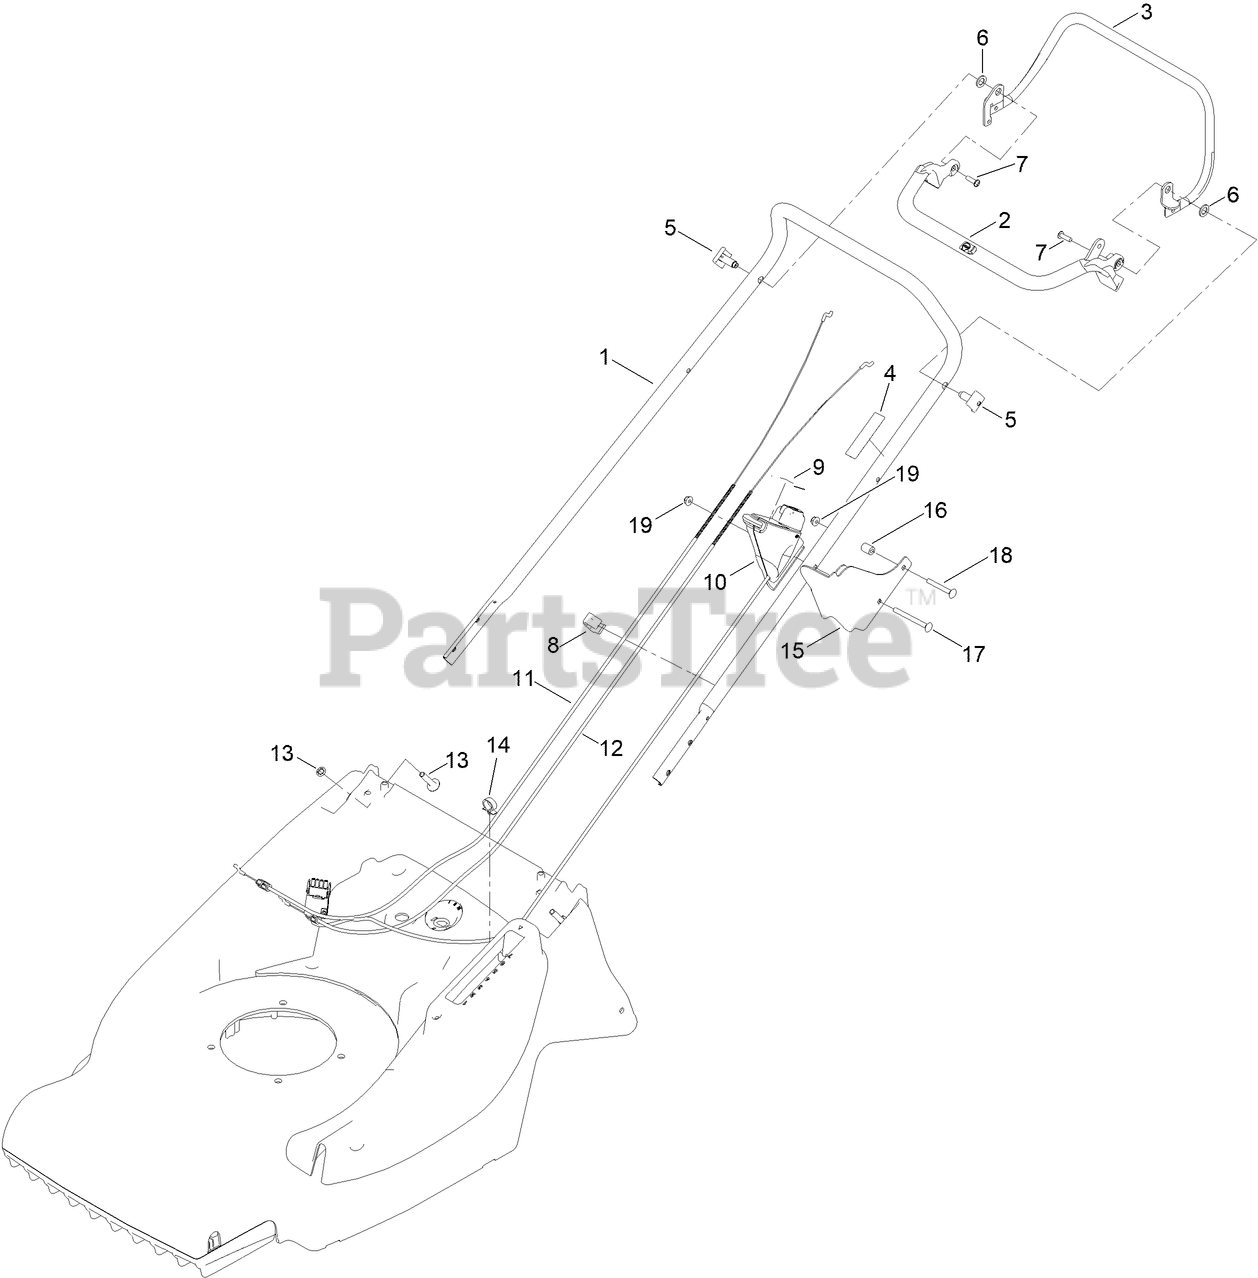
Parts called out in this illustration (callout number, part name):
1	UPPER HANDLEBAR [BLACK]
2	OPC LEVER - ENGINE
3	LEVER-CLUTCH, GEARBOX
4	DECAL BUTON PUSH 60V
5	PIN-PIVOT
6	WASHER-NYLON
7	SCREW
8	GUIDE-CABLE
9	DECAL - SWITCH
10	SWITCH-STARTER-WHEEL-ASM, HANDLE
11	OPC CABLE, 2X 60V
12	DRIVE CABLE, 2X 60V
13	GRIP-FIX
13	BOLT-COACH
14	CLIP, OMEGA,
15	GUARD-HOUSING, SWITCH
16	SPACER
17	SCREW-CARR
18	SCREW-CARR
19	NUT-HF
